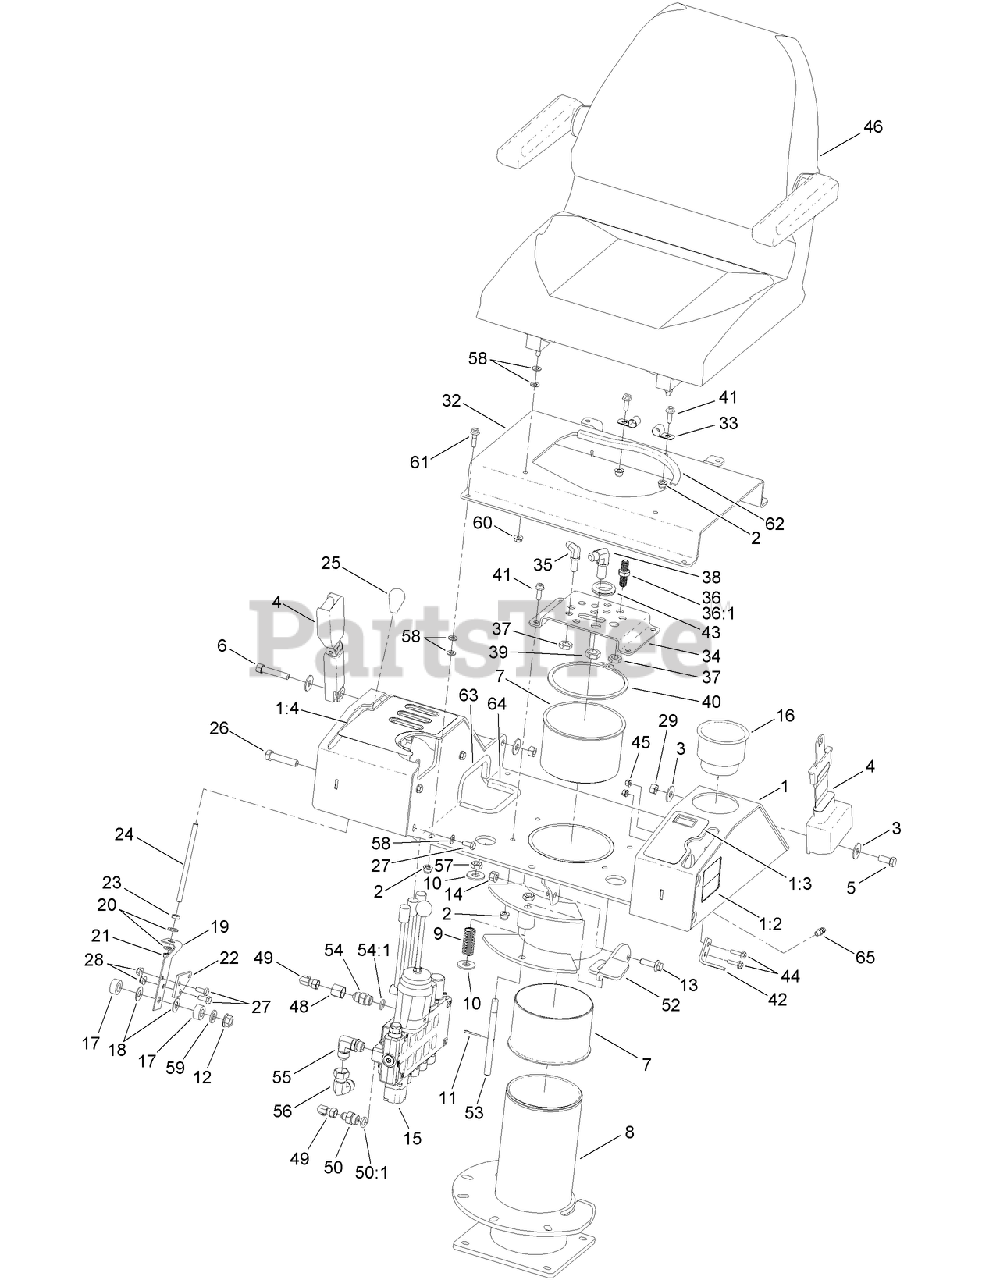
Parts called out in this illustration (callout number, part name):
1	SEAT PLATE ASM
1:2	DECAL-WARNING, NO RIDERS
1:3	DECAL-CONTROL, LH
1:4	DECAL-CONTROL, RH
2	NUT-TORQUE, PREVAILING
3	WASHER-FLAT
4	SEAT BELT ASM
5	SCREW-HH
6	BOLT-BLADE
7	PIVOT-BEARING SEAT
8	MOUNT-SEAT
9	SPRING-PIVOT LOCK, SEAT
10	WASHER-FLAT
12	NUT-HF
13	SCREW-HHF
14	NUT-LOCK, NI
15	HYD CONTROL VALVE ASM
16	CUP-HOLDER
17	SPACER-GEARBOX
18	WASHER-FRICTION
19	LEVER-CONTROL, SPEED
20	WASHER-FLAT
21	NUT-HEX
22	PLATE-MOUNTING, CABLE
23	NUT-JAM
24	ROD-LINKAGE
25	KNOB-CONTROL
26	SCREW-HH
27	SCREW-HH
28	NUT-HF, NI
29	NUT-HEX
32	MOUNT-SEAT
34	PLATE-BULKHEAD, SEAT
36	UNION-BULKHEAD
36:1	NUT-LOCK, BULKHEAD
37	NUT-LOCK, BULKHEAD
39	NUT-LOCK
40	RING-RETAINING
41	SCREW-HH
42	PLATE-MOUNT
43	GROMMET-RUBBER
44	SCREW-HHF
45	NUT-FLANGE, NI
46	SEAT ASM
48	REDUCER-TUBE
49	ELBOW-SWIVEL, 90 DEG
50	CONNECTOR
50:1	O-RING
52	BRACKET-SEAT
53	ROD-SWING, SEAT
54	FITTING-STRAIGHT
54:1	O-RING
55	ADAPTER
56	ADAPTOR
57	NUT-JAM
58	WASHER-PLAIN
59	WASHER-FLAT
60	NUT-HF, LOCK
61	SCREW-HHF
62	TRIM-BATTERY
63	TRIM-BASE, CONTROL
64	TRIM-BASE, CONTROL
65	FITTING-GREASE
